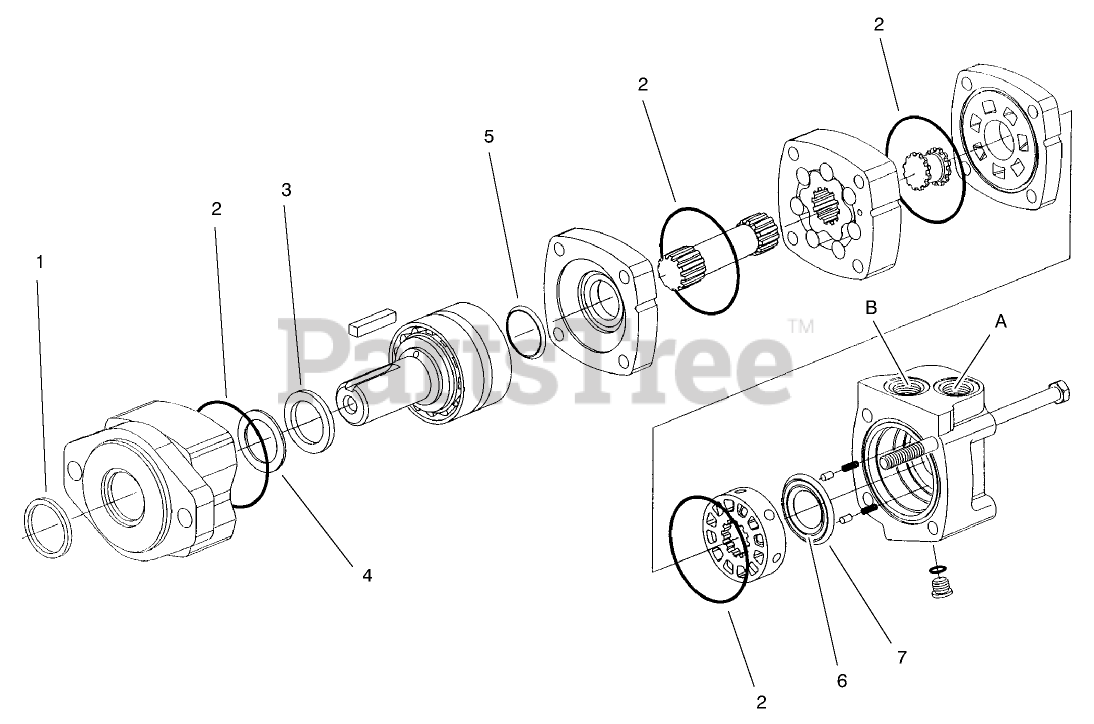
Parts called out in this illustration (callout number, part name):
2	Seal-O-Ring
4	Back-Up Washer
7	Seal-Outer
